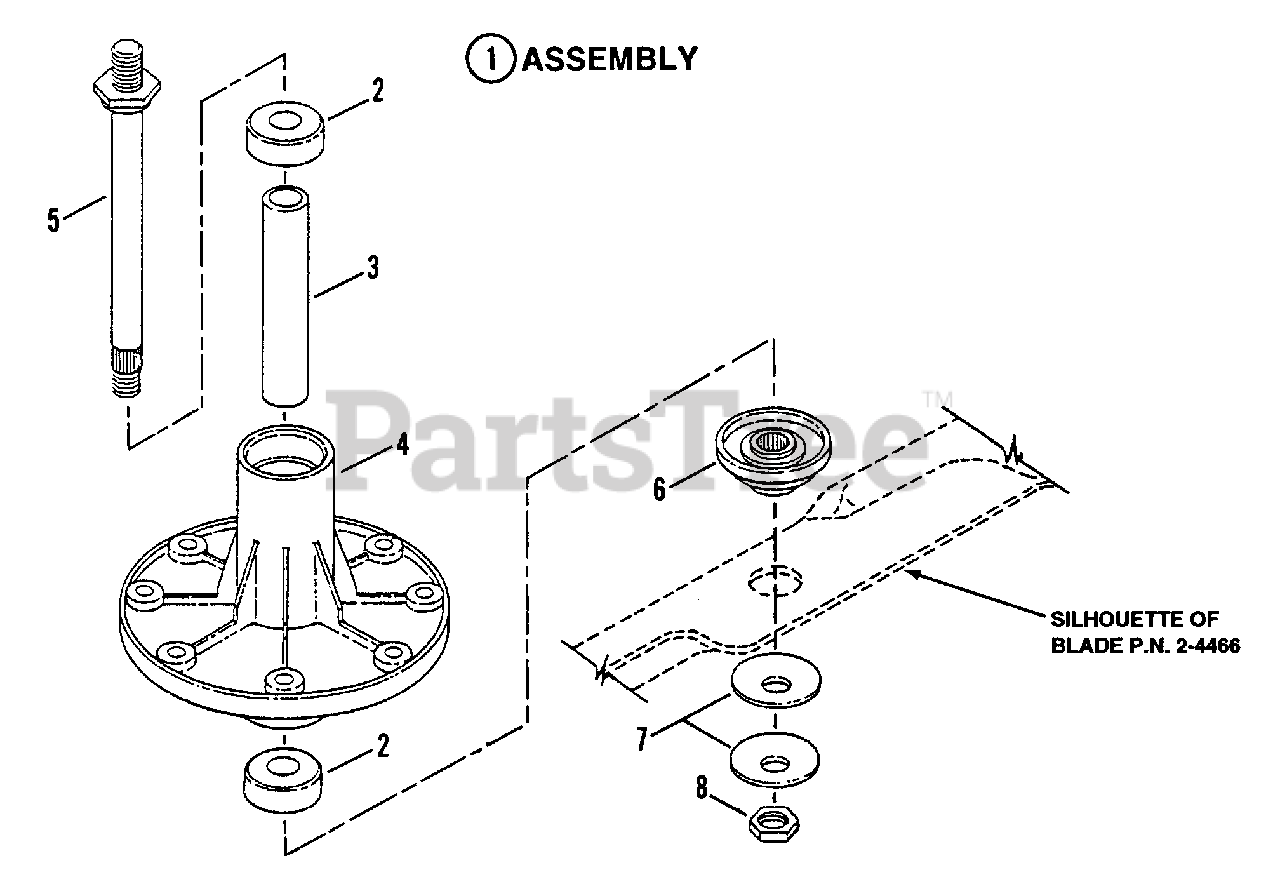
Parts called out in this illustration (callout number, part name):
1	ASSEMBLY, Spindle Housing, 38" Cutting Deck
2	BEARING, Spindle
3	SPACER, Spindle Housing
4	HOUSING, Spindle
5	SPINDLE, (6.899")
6	SPACER, Blade
7	WASHER, Belleville, 19/32" I.D., 1 3/4" O.D.
8	NUT, 9/16-18 Hex Jam
